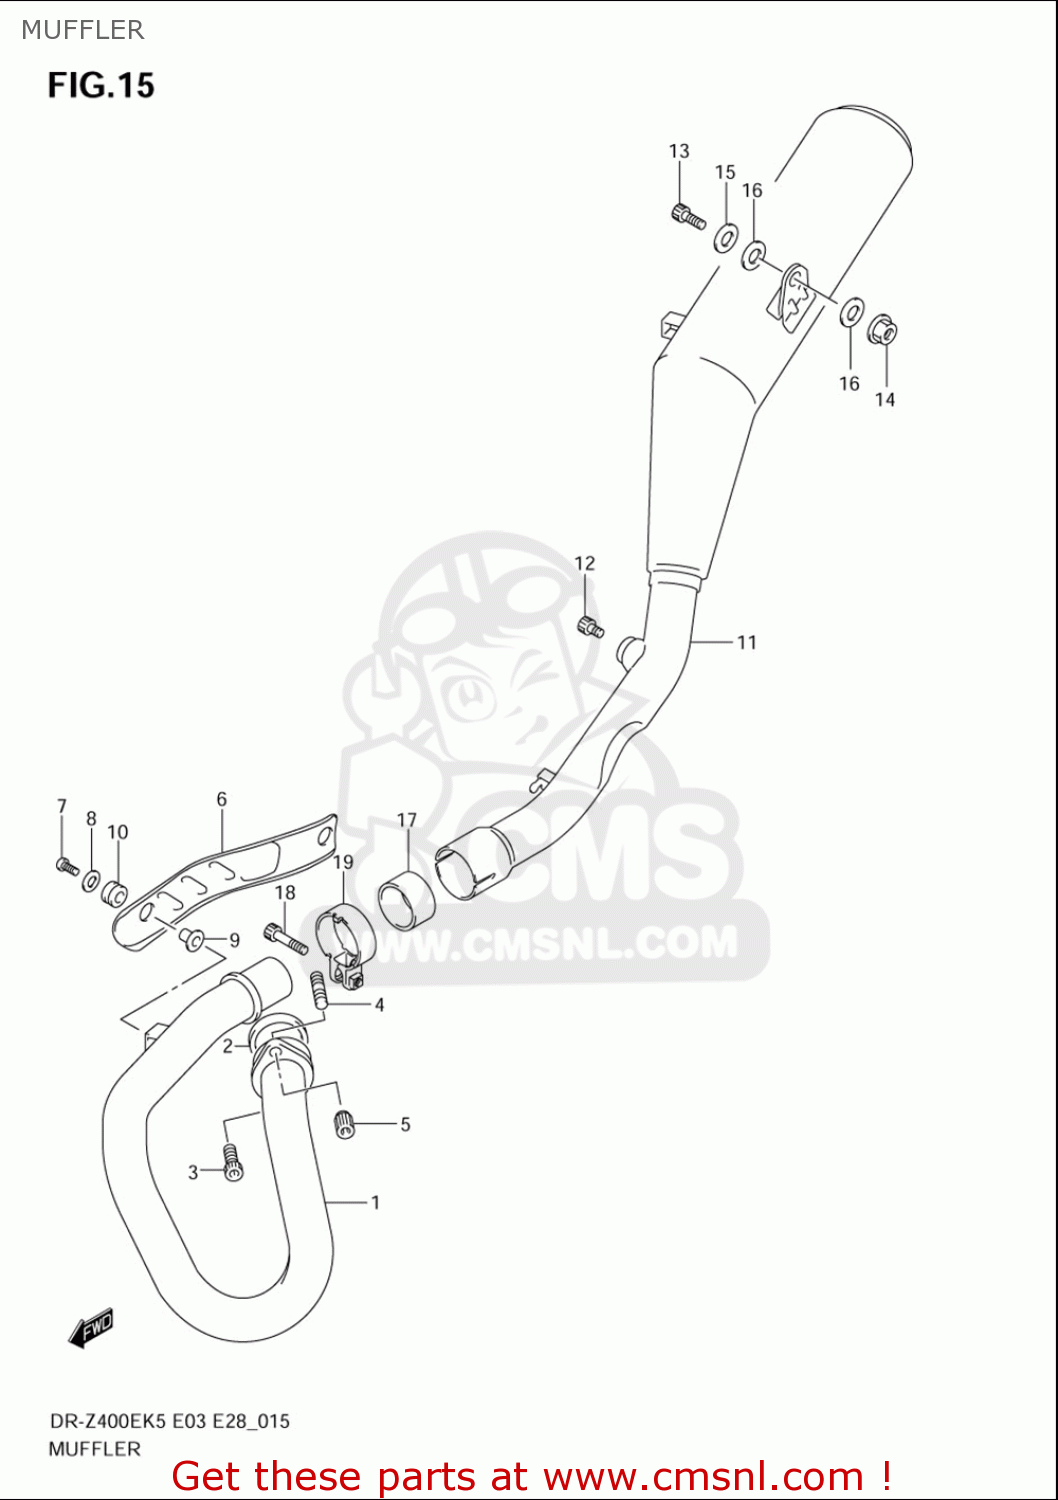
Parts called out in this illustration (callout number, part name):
1	PIPE,EXHAUST
2	GASKET,EXHAUST PIPE
3	BOLT
4	BOLT
5	NUT
6	COVER,EXHAUST PIPE
7	SCREW(6X16)
8	WASHER(6.5X18X1)
9	SPACER(6.2X8.4X6.9)
10	CUSHION
11	BODY,MUFFLER
12	BOLT
13	BOLT
14	NUT
15	WASHER(8.5X24X2.3)
16	WASHER
17	CONNECTOR,MUFFLER JOINT
18	BOLT
19	CLAMP,MUFFLER CONNECTOR
